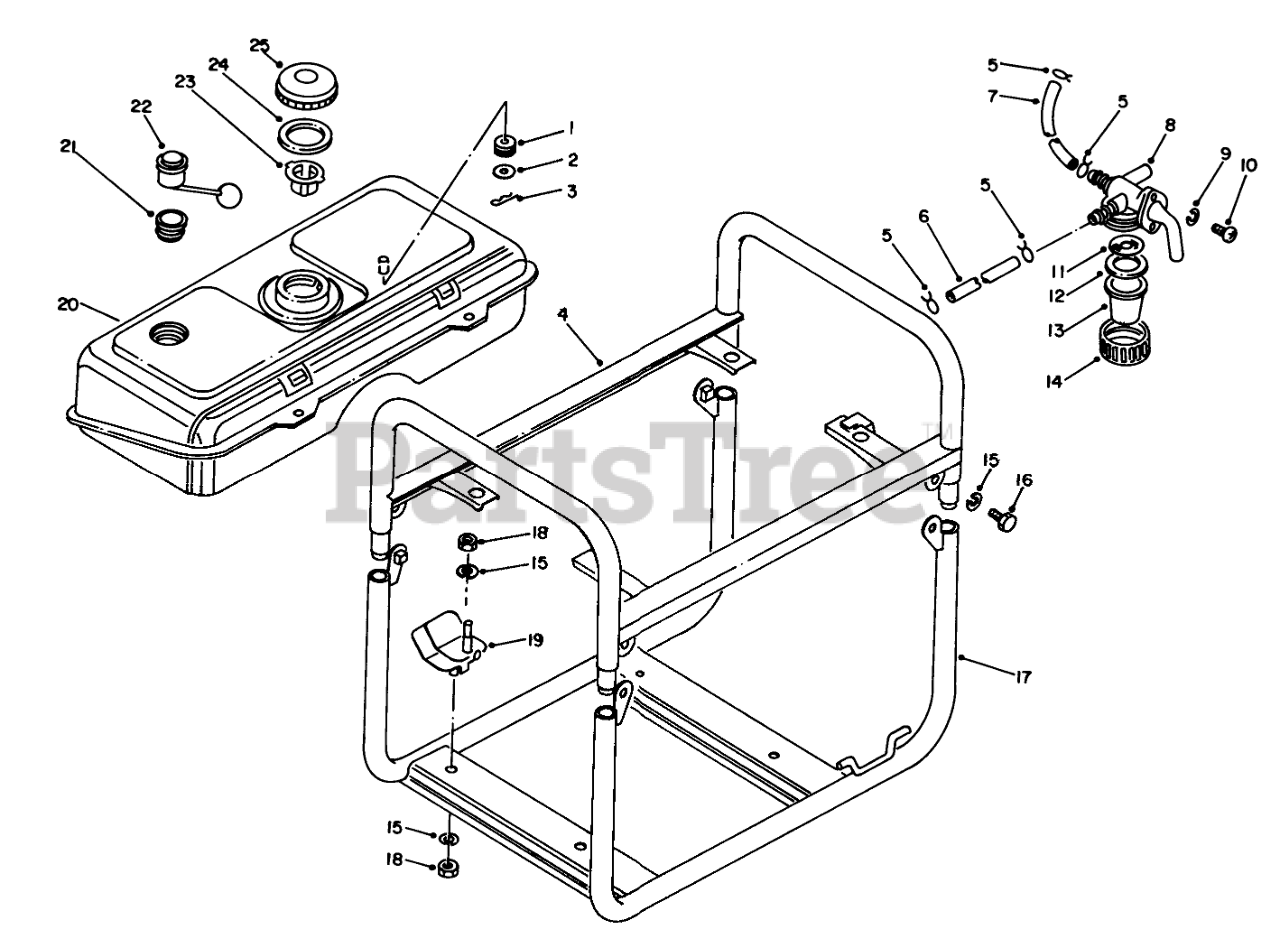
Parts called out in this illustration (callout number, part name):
1	CUSHION
2	WASHER
4	Frame-Upper
8	Cock Assembly Fuel (Incl. Ref. #11-14)
9	Lockwasher
10	Screw
11	FILTER
12	GASKET
15	WASHER-LOCK
17	Frame-Lower
18	Nut
19	Mounting-Engine
20	Tank-Fuel
21	Gasket
22	FUEL GAUGE ASM
23	Filter
24	GASKET
